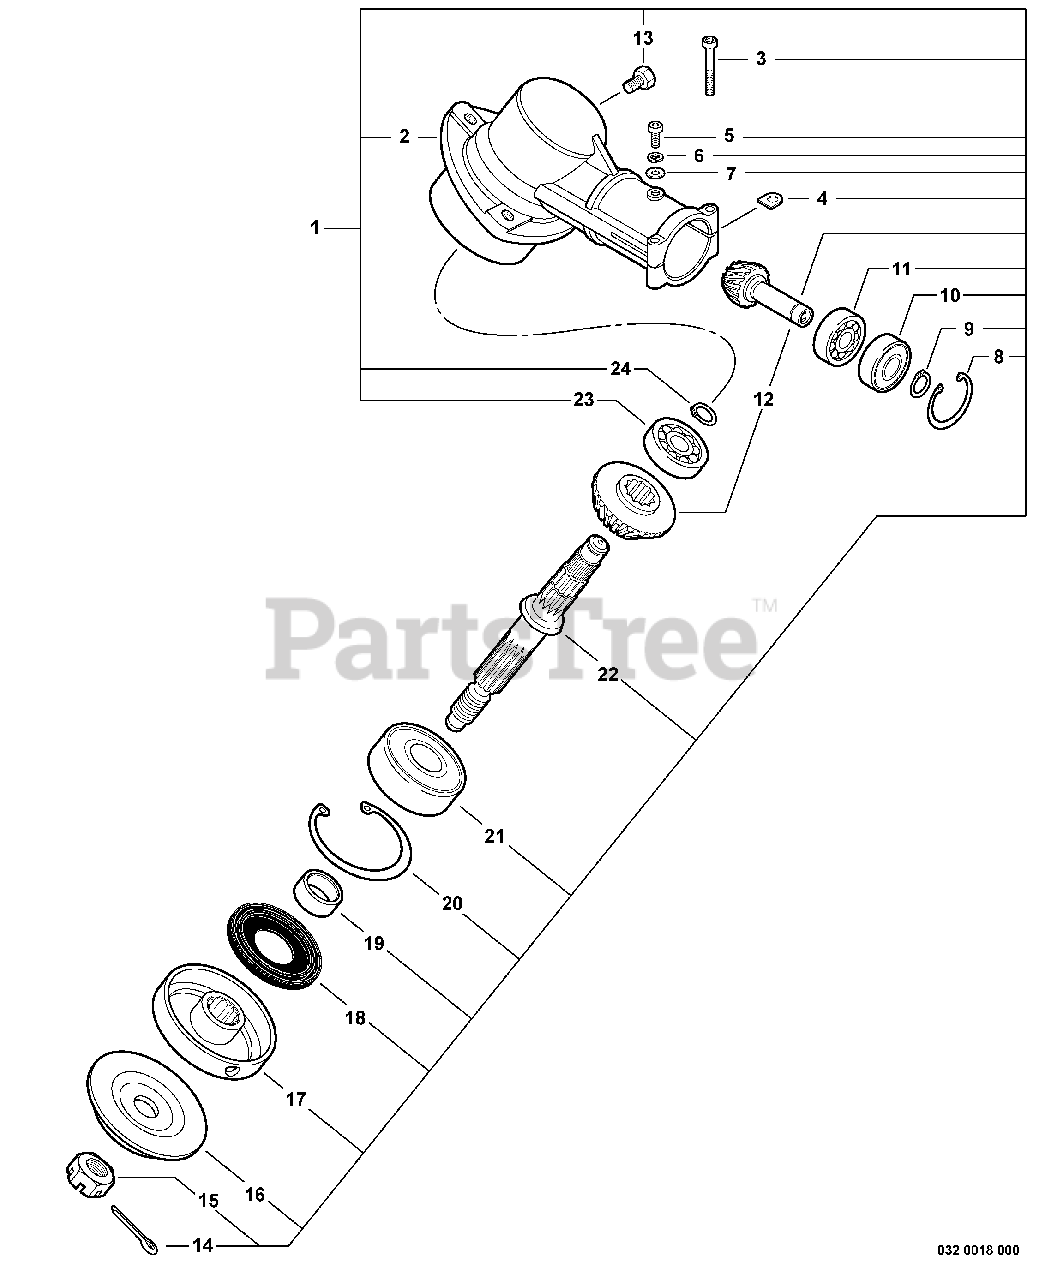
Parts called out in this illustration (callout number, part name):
1	GEAR CASE ASSY
2	CASE, GEAR
3	SCREW - 5X25
5	SCREW - 5X12
6	LOCKWASHER - 5
7	WASHER - 5
8	RING, RETAINING - 22
9	RING, RETAINING - 10
10	BEARING, BALL - 6900Z
11	BEARING, BALL - 6900
12	GEAR SET - BEVEL
13	BOLT - 8X8
14	PIN, SPLIT - 2X22
15	LOCKNUT - LEFT HAND
16	ADAPTOR, BLADE - LOWER
17	ADAPTOR, BLADE - UPPER
18	SEAL, OIL
20	RING, RETAINING - 32
21	BEARING, BALL - 6201
22	GEAR - SHAFT
23	BEARING, BALL - 609
24	RING, RETAINING - 12
